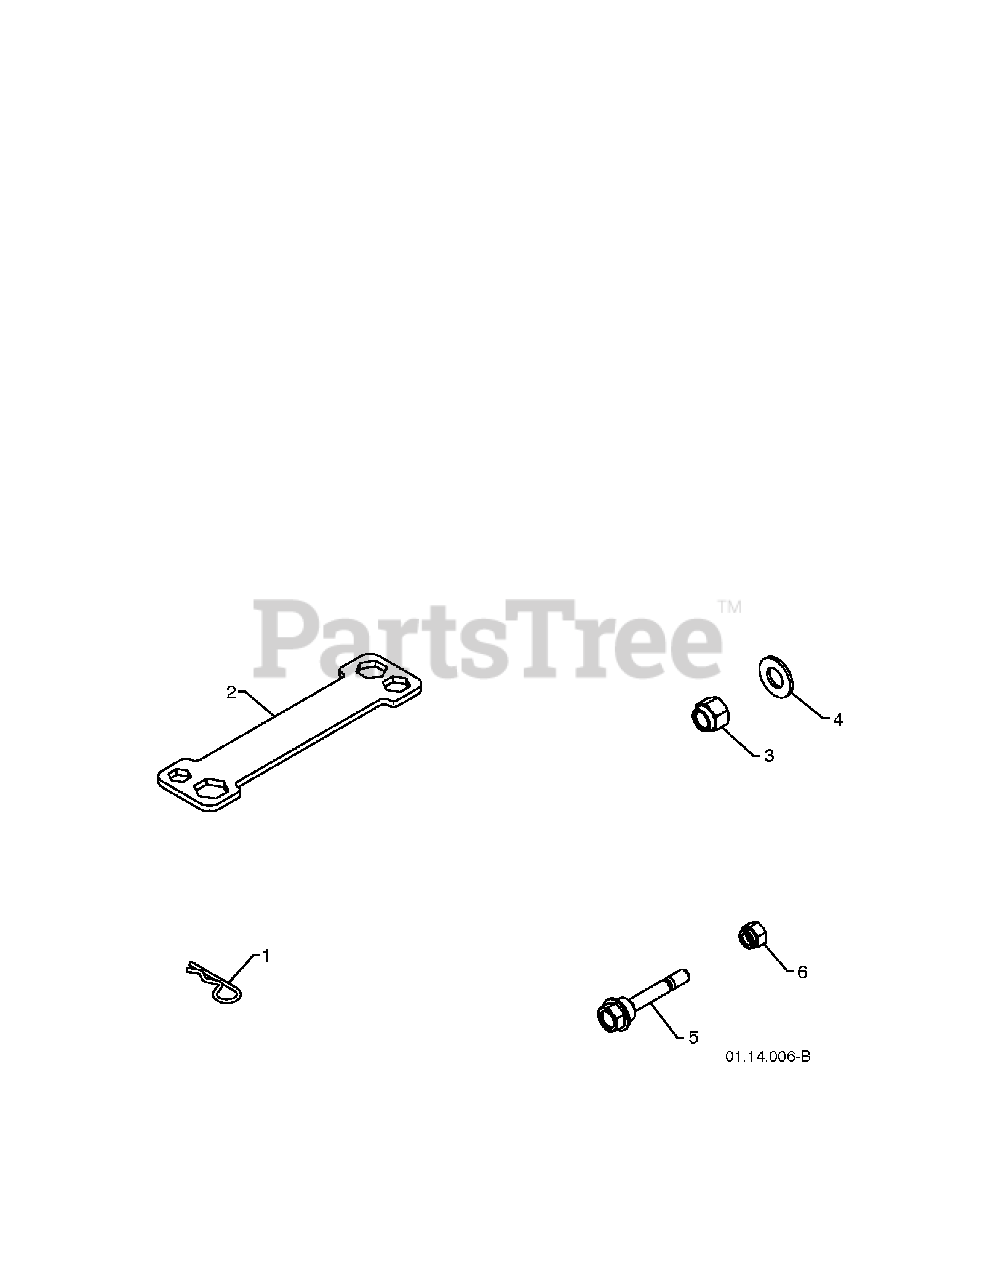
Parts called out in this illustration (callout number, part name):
1	SPRING RETAINER
2	WRENCH.SNOWTHROWER
3	NUT
5	BOLT, SHOULDER SHEAR
6	LOCKNUT
